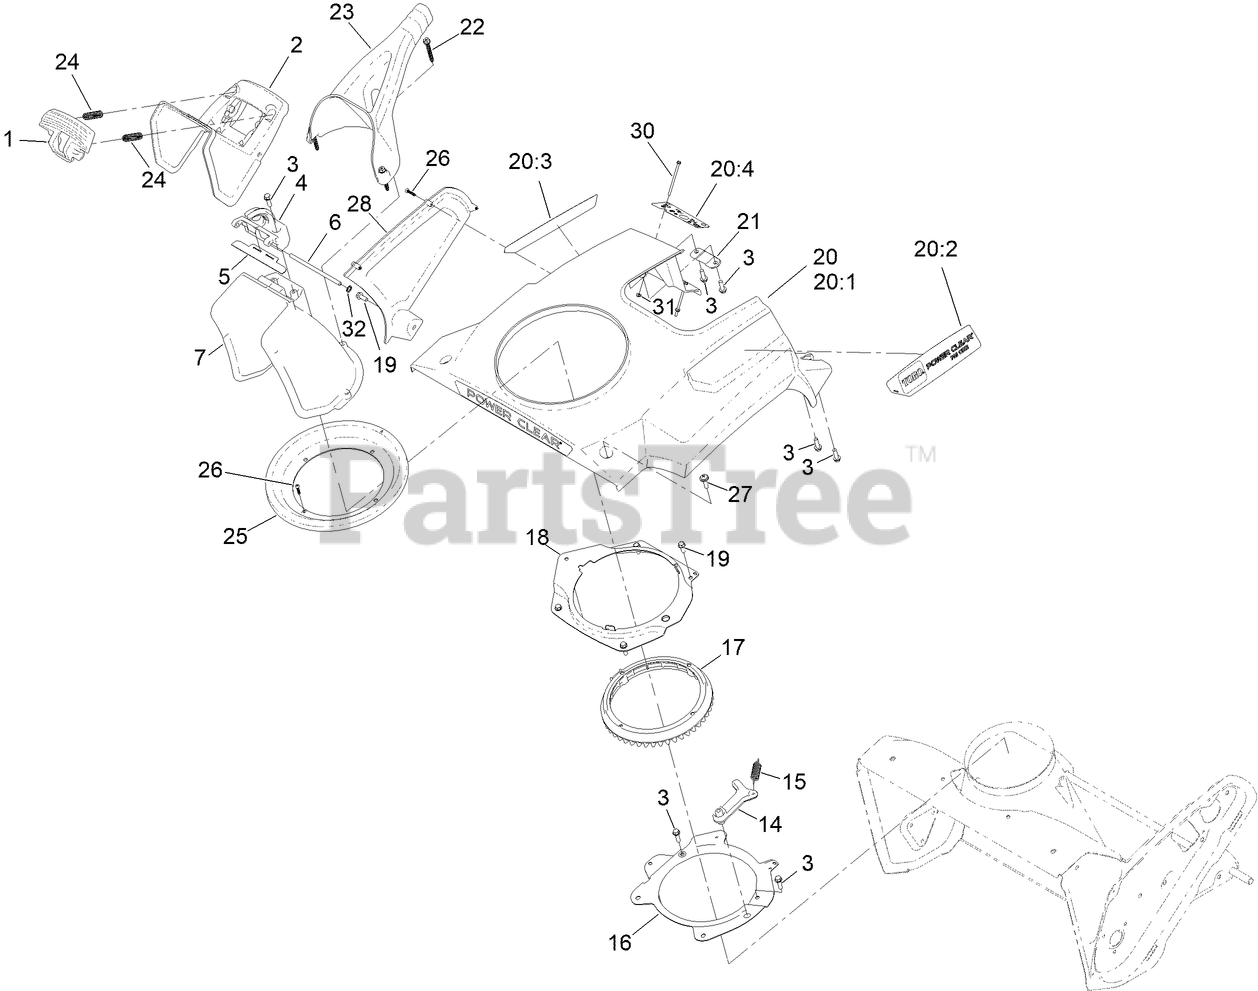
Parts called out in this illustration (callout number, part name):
1	TRIGGER-DEFLECTOR
2	DEFLECTOR-CHUTE, CE
3	SCREW-HWH
4	HINGE-RATCHET, DEFLECTOR
5	SEAL-DEFLECTOR
6	HINGE PIN-DEFLECTOR
14	PAWL-DETENT
15	SPRING-EXTENSION
16	RING-SUPPORT, CHUTE
17	RING-CHUTE, DETENT
18	RETAINER-RING, CHUTE
19	SCREW-HWH
20	SHROUD ASM, W/DECALS
20:1	SHROUD ASM, W/ARTWORK
20:2	DECAL-SHROUD LH
20:3	DECAL-SHROUD RH
20:4	DECAL-ENGINE, ELECTRIC START
21	RETAINER-SHROUD
22	SCREW-HWH, PLASTITE
23	HANDLE-CHUTE
24	SPRING-COMPRESSION
25	SEAL-RING, CHUTE
26	SCREW-PPH
27	SCREW-PPH
28	COVER-SIDE
30	SCREW-HWH
31	NUT-HEX
32	RING-RETAINING
